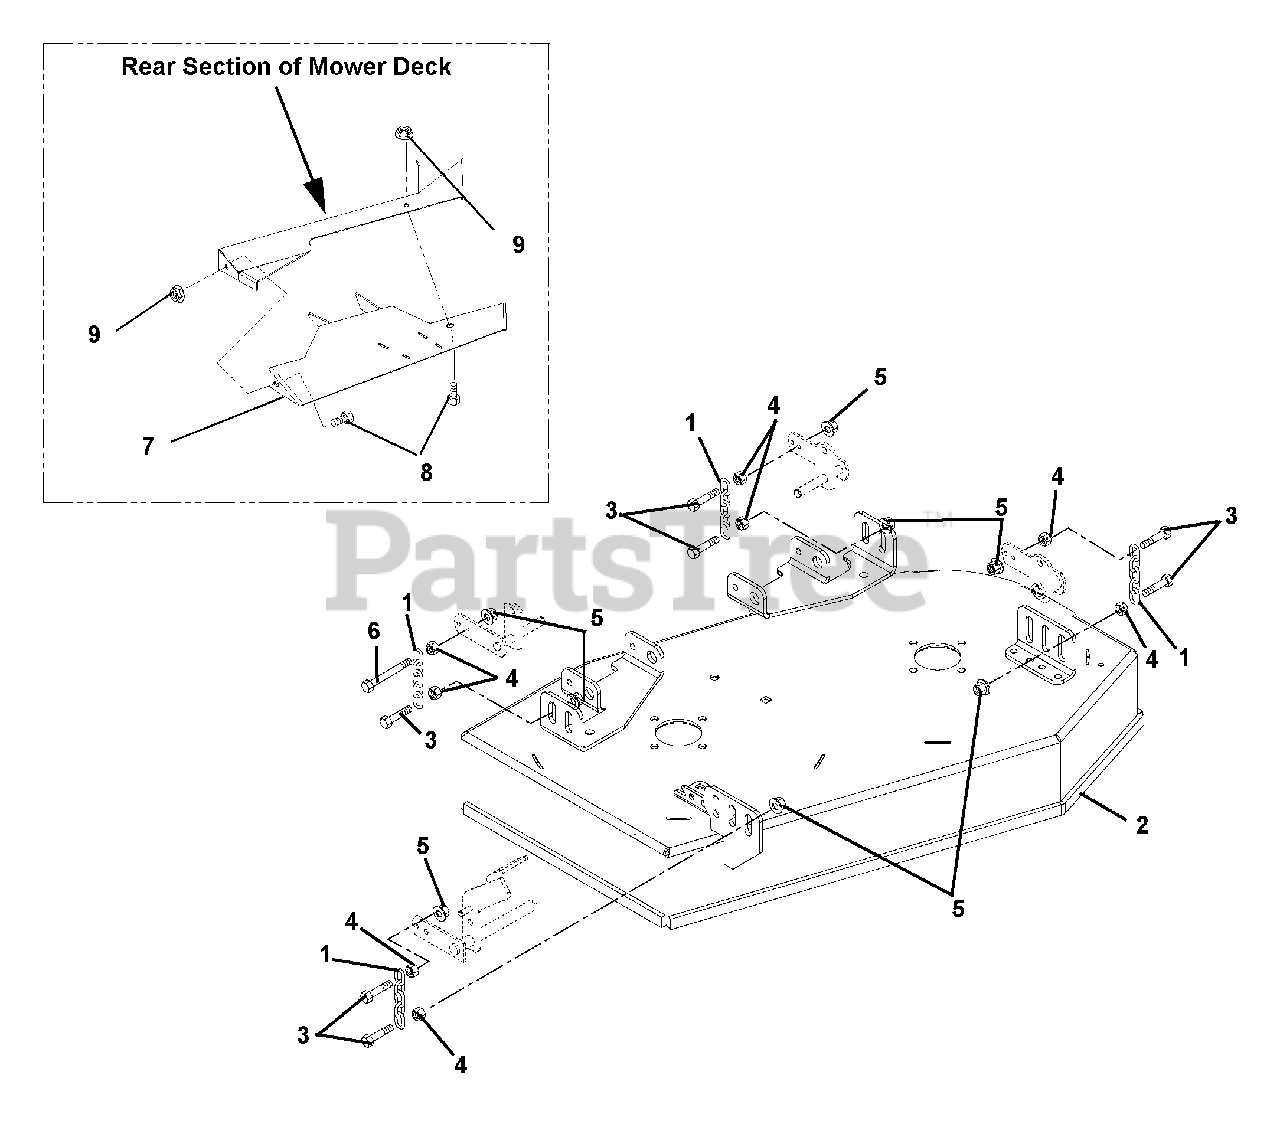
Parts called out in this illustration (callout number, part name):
1	CHAIN, LINK
2	WMT-34" MOWER DECK-REAR DISCH
3	BLT-HEX M12X1.75X55 GR5 YZ
4	NUT-SPNLK-FLG M12-1.75 YZ
5	NUT-LK-TOP-FLG M12-1.75 YZ
6	@BLT-HEX .50-13X3.00 GR5 YWZC
7	WMT-34" DEFLECT EXT-REAR DISCH
8	BLT-HEX .31-18X1.0 YWZC
9	@NUT-LK-TOP-FLG .31-18 YWZC
